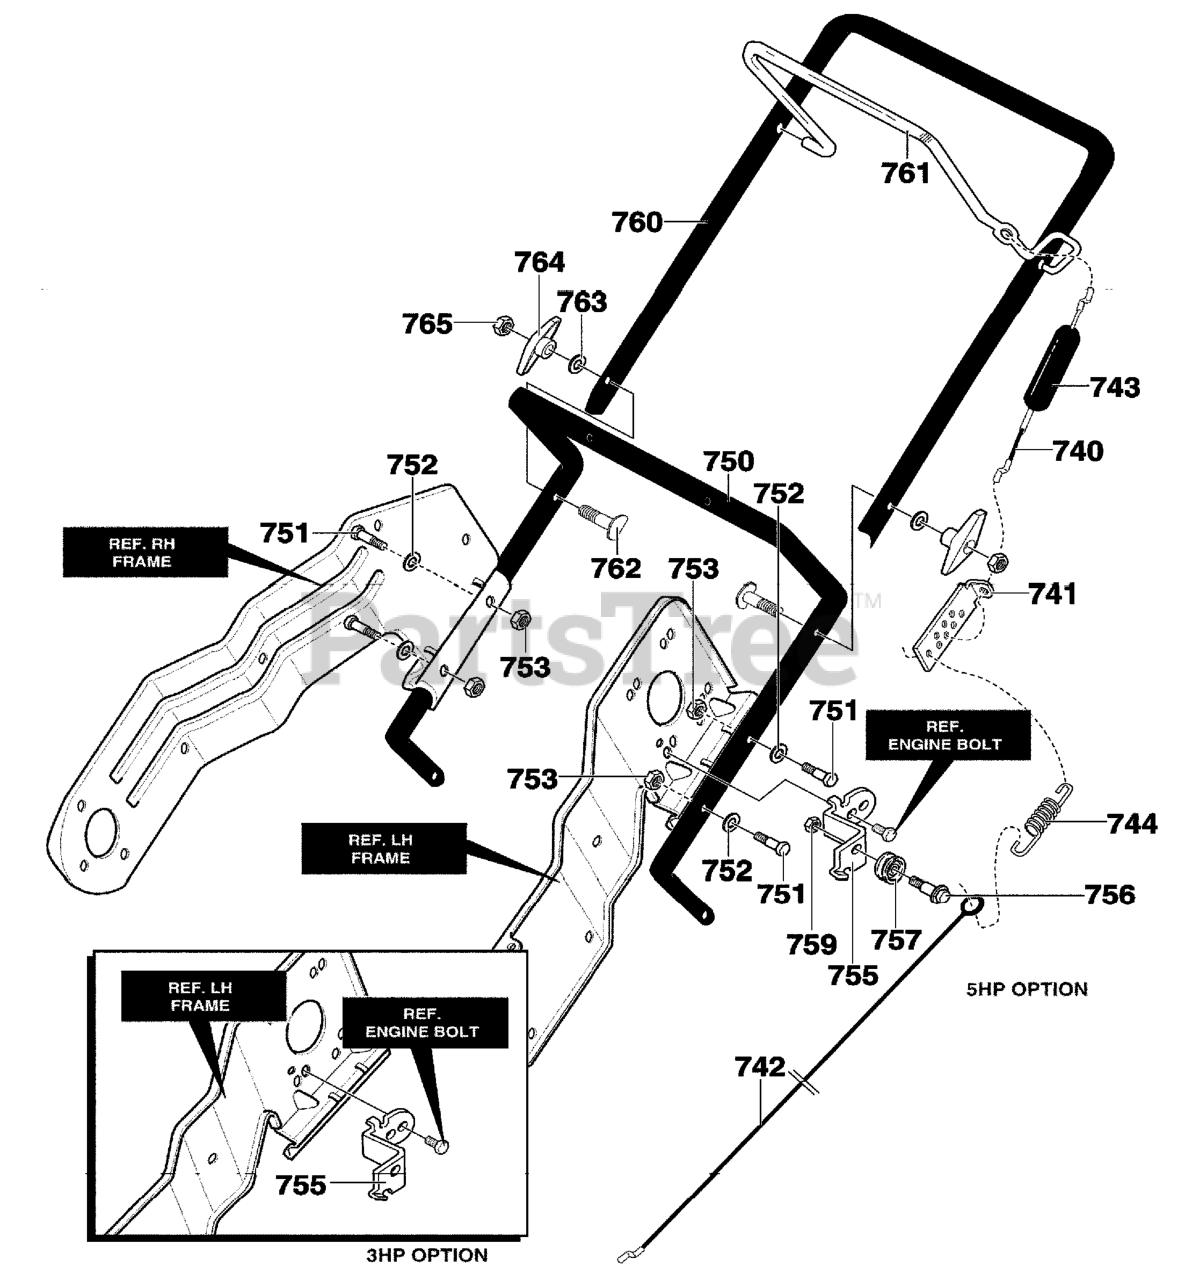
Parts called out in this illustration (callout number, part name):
740	CABLE, UPPER
741	BRACKET, CABLE ADJ
742	CABLE, LOWER CONTROL
743	BOOT, CLUTCH SPRING
744	SPRING, EXTENSION
750	HANDLE, LOWER
751	SCREW, 1/4-20X1.25
752	WASHER, FLAT
753	NUT, 1/4-20
755	BRACKET, CABLE
757	PULLEY, NYLON
759	NUT, 1/4-20
760	UPPER HANDLE
761	BAIL, CONTROL
762	BOLT, 5/16-18X2.00
763	WASHER, FORM
764	T-KNOB
765	NUT, 5/16-18
